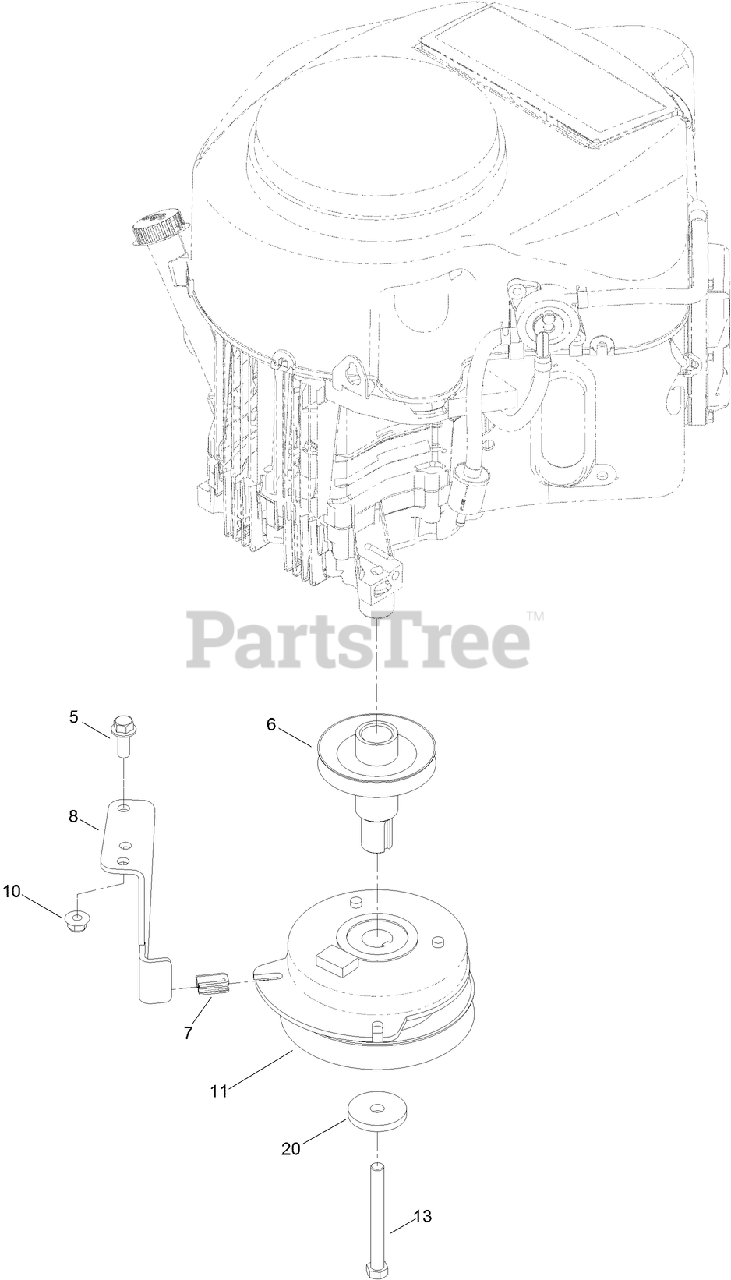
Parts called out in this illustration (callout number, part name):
5	SCREW-HHF
6	PULLEY-ENGINE
7	ISOLATOR-CLUTCH
8	STOP-CLUTCH
10	NUT-HF, NI
11	CLUTCH-PTO
13	SCREW-HH
20	WASHER-CLUTCH
